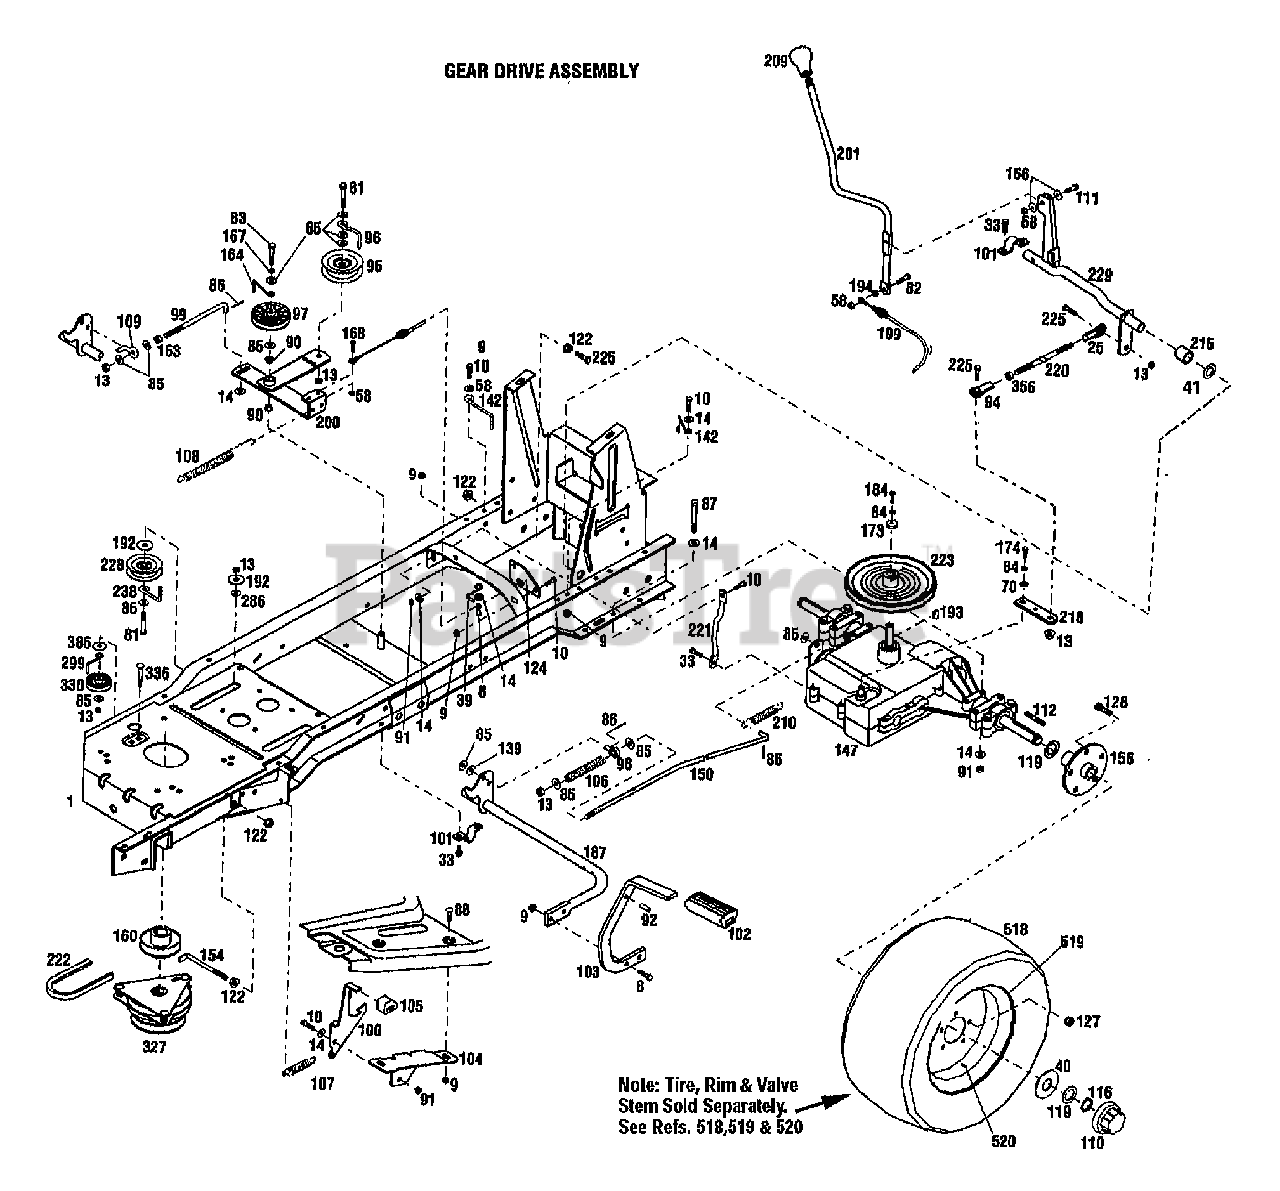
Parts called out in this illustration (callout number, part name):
8	SCR-HH 5/16-18X1.0 G5 ZP
9	NUT-HFLK 5/16-18 ZP
10	SCR-HHC 5/16-18X.75 GR 5 ZP
13	NUT-LOCK 3/8-16
14	WASHER-FLAT 5/16 SAE
25	JOINT-BALL
33	SCR-HFLK 5/16-18X.75
39	GUIDE-BELT
40	WASHER-SPEC .75X2.50
41	WASHER-THRUST
58	NUT-HT LK 1/4-20
70	WASHER-FLAT 1/4 SAE
81	SCR-HH 3/8-16X2.0 G5 ZP
82	SCR-HH 1/4-20X1.0
83	SCR-HH 3/8-16X1.75 G5 ZP
84	WASHER-LK .25 ZP
85	WASHER-FLAT 3/8 SAE
86	PIN-COTTER .09X.75 ZP
87	SCR-HH 5/16-18X2.75 G5 ZP
88	SCR-CARR 5/16-18X.62 G2 ZP
90	BUSHING-.5X.5 NYLON FLNG
91	NUT-TOP/LK 5/16-18 ZP
92	PIN-.312X.75
94	JOINT-BALL
96	GUIDE-BELT
97	PULLEY-IDLER
98	SWIVEL
99	ROD-CLUTCH
100	LATCH-BRAKE CLUTCH USE1771514
101	CLIP-CLAMP .75 ID
102	PAD-FOOT PEDAL
103	PEDAL-BRAKE
104	BRKT-BRAKE LOCK
105	PAD-BRAKE
106	SPRING-COMPRESSION
107	SPRING-EXTENSION
108	SPRING-EXTENSION
109	ROD-PIVOT
110	CAP-HUB
111	SCR-HFLK 1/4-20X1.00
112	KEY-.25 SQ X 2.0
116	RING-RETAINING
119	WASHER-SPEC
122	NUT-HFLK 3/8-16 ZP
124	SUPPORT-CABLE
127	NUT-LUG 7/16-20
128	BOLT-WHEEL
139	WASHER-.376 DIA
142	GUIDE-BELT
147	TRANSAXLE
150	ROD-BRAKE
154	RETAINER-CLUTCH
156	HUB-WHEEL
160	PULLEY-ENGINE
163	NUT-HEX 3/8-16 ZP
164	GUIDE-BELT
166	WASHER-FLAT 1.25X.28X.062 ZP
167	WASHER-LK .375 @ DEPL
168	SCR-HH 1/4-20X.75 G5 ZP
173	WASHER-.865X.281X.1793
174	SCR-HHC 1.4-28 X .50
184	SCR-HH 1/4-20X1.25
187	ASSM-BRAKE PEDAL
192	WASHER-1.12X.378X.125
193	KEY-WOODRUFF .188X.75
194	NUT-HEX 1/4-20 ZP
199	CABLE-SHIFT
200	PLATE-IDLER
201	ARM-SHIFT
210	SPRING-EXTENSION
215	SPACER
218	ARM-TRANSMISSION
220	ROD-ADJUSTING
221	SUPPORT-TRANSMISSION
222	BELT-V
223	PULLEY-TRANSMISSION
225	SCR-HH 3/8-16X1.25
228	IDLER-SHEAVE 3" X 1"
229	SHAFT-PIVOT
238	GUIDE-BELT
286	WASHER-.75X.406X.092
299	GUIDE-BELT
327	CLUTCH-ELECTRIC
330	PULLEY-IDLER
336	BOLT-CARR
356	NUT-HEX/JAM 3/8-24 ZP
386	WASHER-1.06X.531X.1 ZP
519	RIM-WHEEL REAR
520	STEM-VALVE
